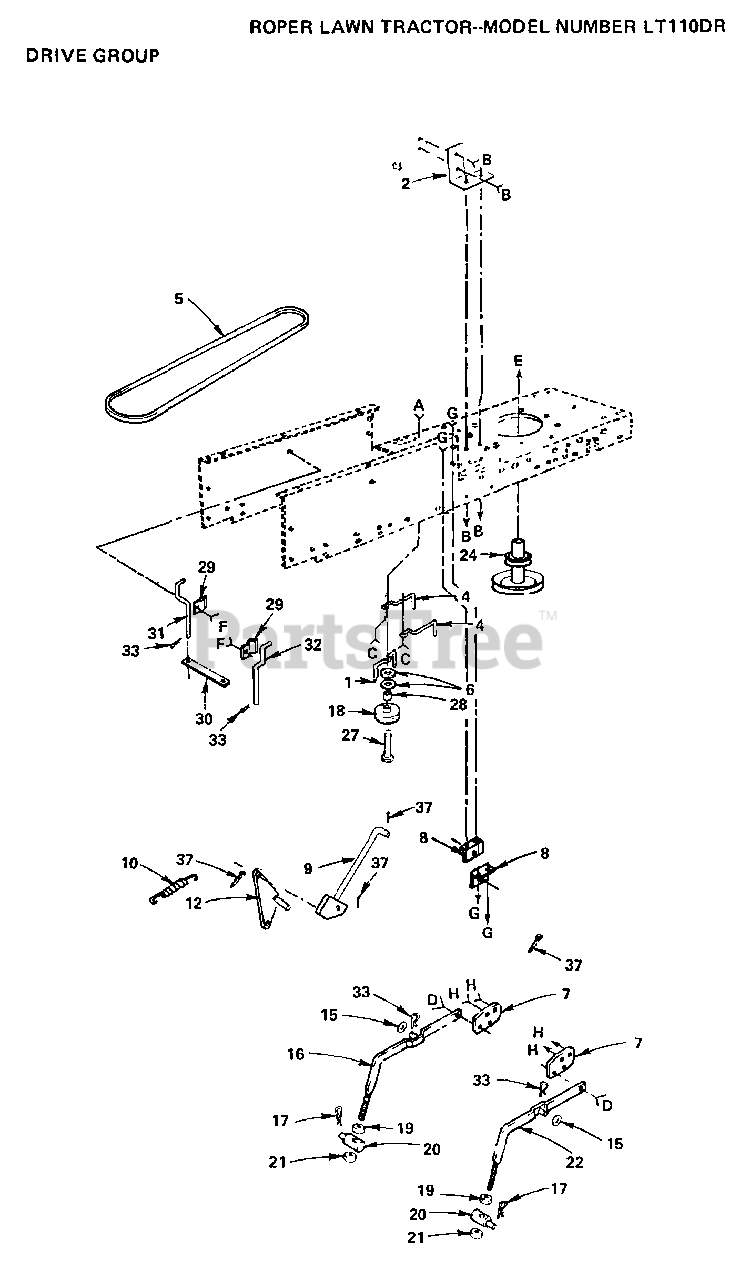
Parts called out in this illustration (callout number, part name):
2	BRACKET LT
4	"KEEPER,BLT ENG LT"
6	WASHER
7	"BRACKET, SUSPE T"
8	"BRKT,BELLCRAN T"
9	ROD ASSEM YT
17	SPRING H
19	NUT
21	NUT LTV
27	BOLT
28	SPACER T
29	CLAMP LT
33	SPRING.RETAINER
37	COTTER PIN
